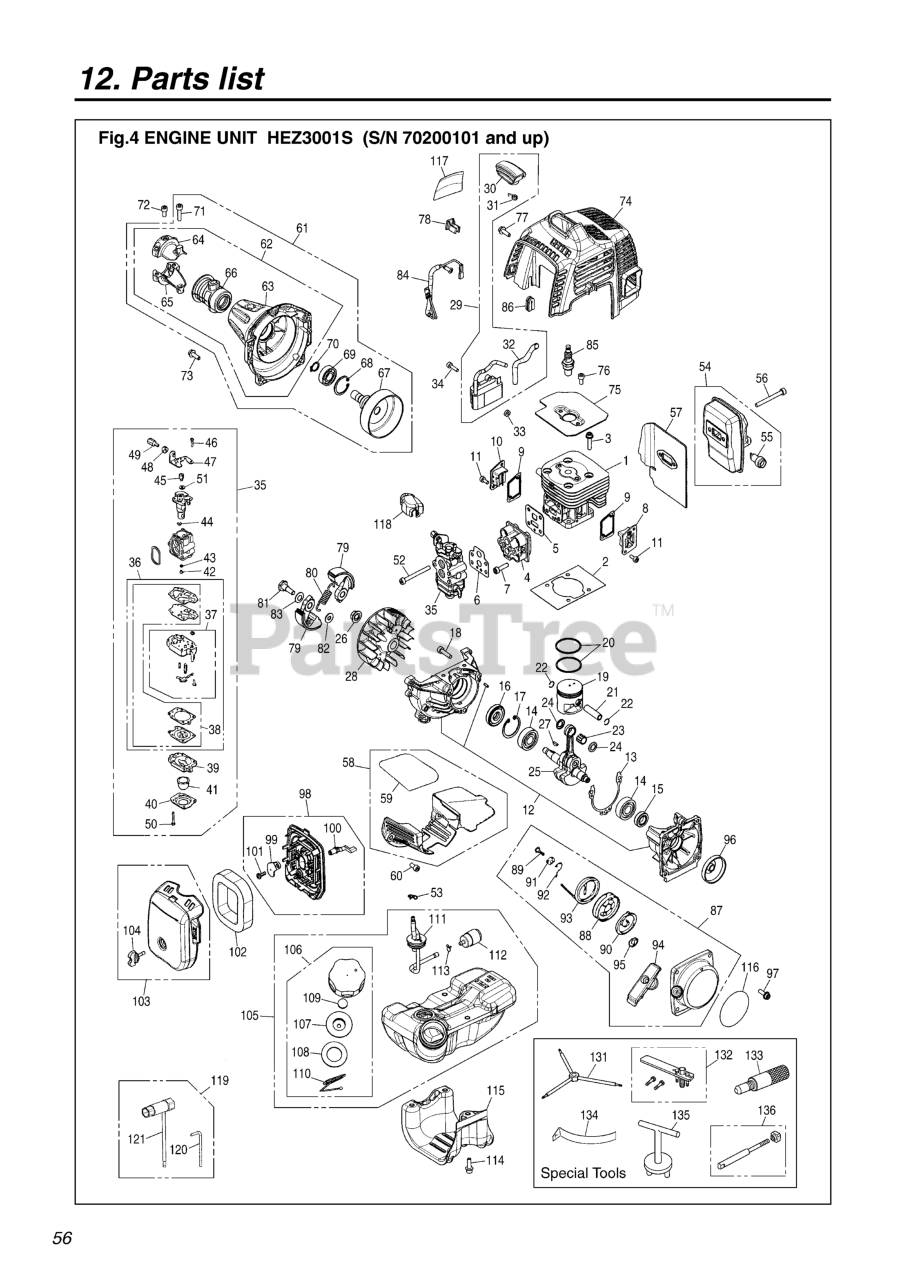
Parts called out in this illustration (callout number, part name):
1	CYLINDER (RPLS 848-F60-12A2)
2	GASKET, BASE
3	BOLT
4	INSULATOR
5	GASKET,INSUL.(RPLS.T1590-13120
6	GASKET, CARBURETOR
7	BOLT, TORX
8	COVER, TRS
9	GASKET, TR
10	COVER,TRF (REPLACES -12D1)
11	BOLT, TORX
12	CRANKCASE-C
13	GASKET, CASE
14	BEARING
15	SEAL
16	SEAL, OIL (RPLS 1200-21220)
17	RING, SNAP, M32 x 1.2
18	BOLT (RPLS 2850-14220)
19	PISTON
20	RING
22	RING, SNAP
23	BEARING
24	WASHER (RPLS 3310-41341)
25	CRANKSHAFT-C
27	KEY
28	ROTOR
29	COIL-A
30	CAP (RPLS 4810-72110)
31	SPRING
33	SPACER (RPLS -71260)
34	BOLT TORX
35	CARBURETOR ASSY
36	REBUILD KIT
37	BODY, PUMP
38	KIT, GASKET (REPLACES-06020)
39	BODY, PURGE
40	COVER, PUMP
41	PUMP, PRIMING
42	JET (REPLACES 4810-81250)
43	RING, O
44	RING
45	SWIVEL
46	SCREW
48	NUT, CABLE ADJUSTER
49	SCREW, CABLE ADJUSTER
50	SCREW
51	WASHER
52	BOLT
53	CLIP
54	MUFFLER ASSY
55	ARRESTER
56	BOLT
57	GASKET, MUFFLER
58	PLATE-A
59	SHEET
60	BOLT
61	HOUSING ASSY
62	HOUSING COMP.
63	HOUSING
64	BRACKET (A) (RPLS -31211)
65	BRACKET (B)
66	CUSHION (RPLS -31231)
67	DRUM (REPLACES 4810-31122)
68	RING, SNAP, M28 x 1.2
69	BEARING
70	RING, SNAP (RPLS 3130-13270)
71	BOLT (RPLS 2850-14220)
72	BOLT
73	BOLT
74	COVER, ENGINE
75	PLATE, CYL
76	BOLT
77	BOLT, TORX
78	CLAMP
79	SHOE
80	SPRING
81	BOLT
82	WASHER, FLAT (USE 182303)
83	WASHER (RPLS -51241)
84	CORD COMP.
85	SPARK PLUG (CMR7H)
86	GROMMET
87	RECOIL-A
88	REEL
89	SCREW
90	SPRING, SPIRAL
91	COLLAR
92	ARM
93	ROPE (REPLACES 4500-75160)
94	KNOB (RPLS -75420)
95	PLATE, STOPPER
96	PULLEY
97	BOLT, TORX
98	BODY ASSY (RPLS T1551-82100)
99	PLATE, CHOKE
100	LEVER
101	SCREW
102	ELEMENT
103	COVER-A (RPLS T1551-82200)
104	KNOB
105	TANK ASSY
106	CAP ASSY (RPLS -85201)
107	HOLDER (REPLACES -85230)
108	PACKING
109	FILTER
110	STOPPER
112	FILTER ASSY
113	CLIP
114	BOLT (USE 848-815-2000)
115	GUARD, TANK
116	LABEL, RECOIL
117	LABEL, COVER
118	COVER
119	TOOL SET
120	BAR
121	SOCKET
131	WRENCH (RPLS. 2670-96410)
132	PULLER ASSY
133	STOPPER (TOOL)
134	GUAGE, AIR GAP (TOOL)
135	PULLER, RECOIL (TOOL)
136	ROD-A
